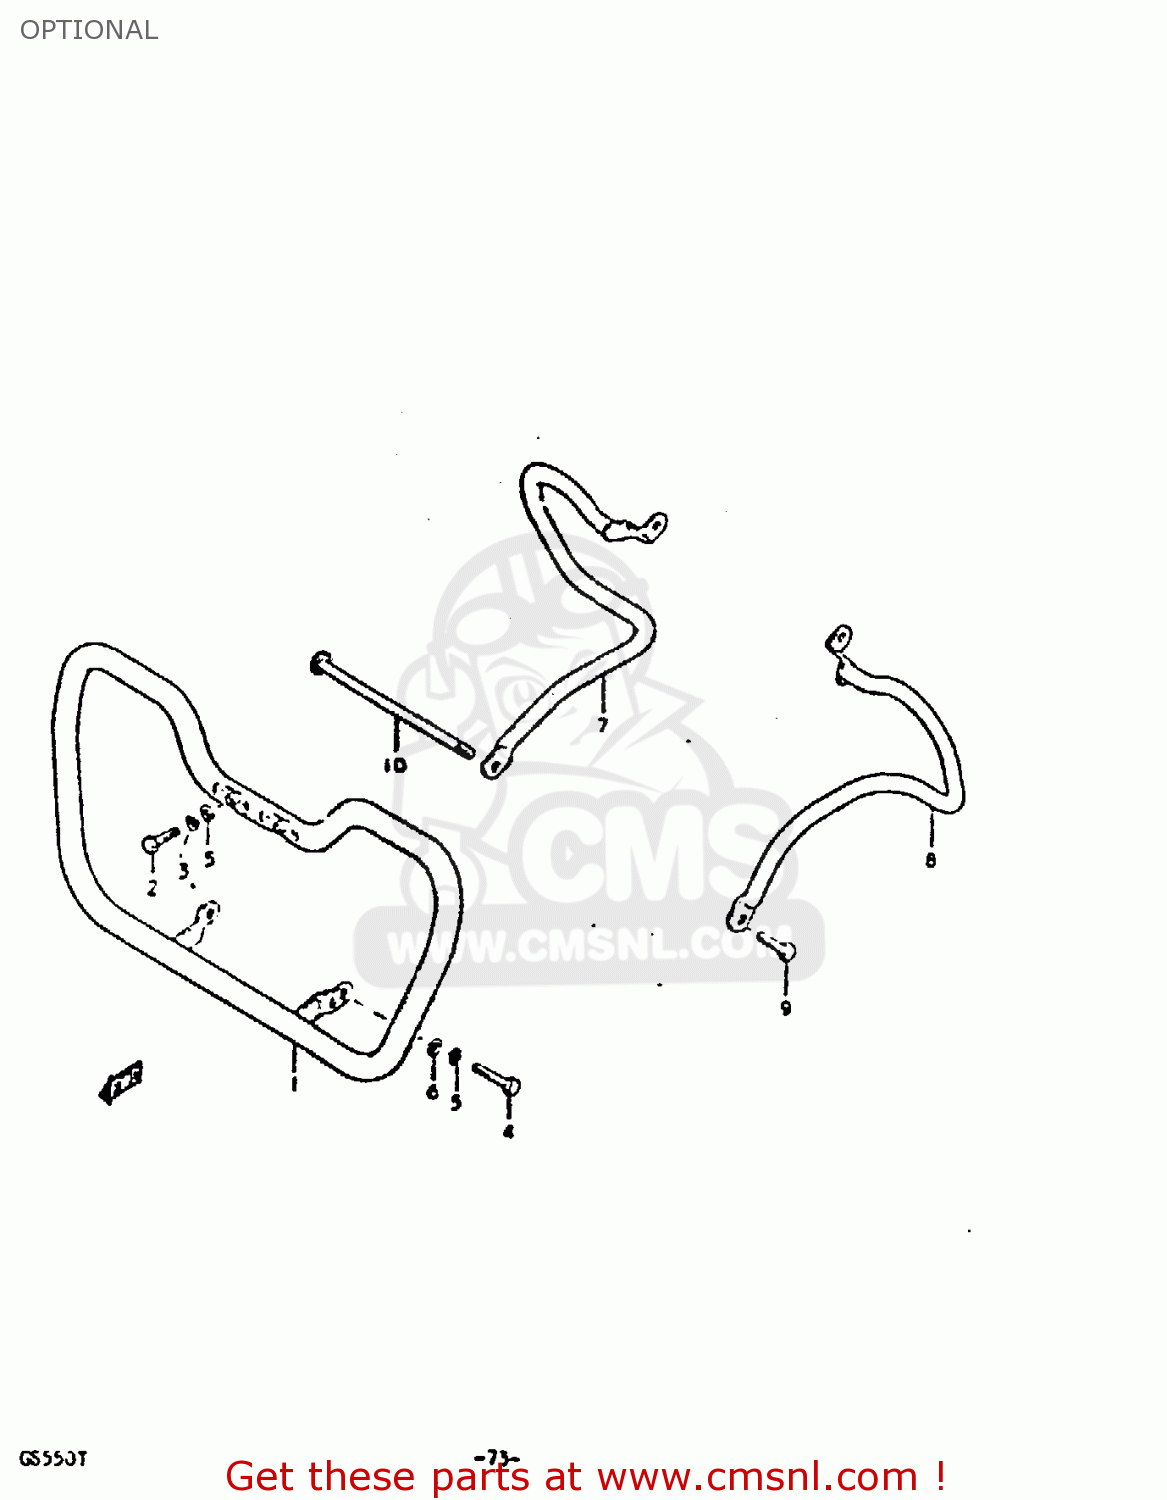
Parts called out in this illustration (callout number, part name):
1	BUMPER
2	BOLT 8X40
3	LOCK WASHER
4	BOLT
5	LOCK WASHER
6	WASHER (8.7X22X2)
7	ACCESSORY BAR,REAR RIGHT
8	ACCESSORY BAR,REAR LEFT
9	BOLT(10X48)
10	SHAFT,REAR SWING ARM
